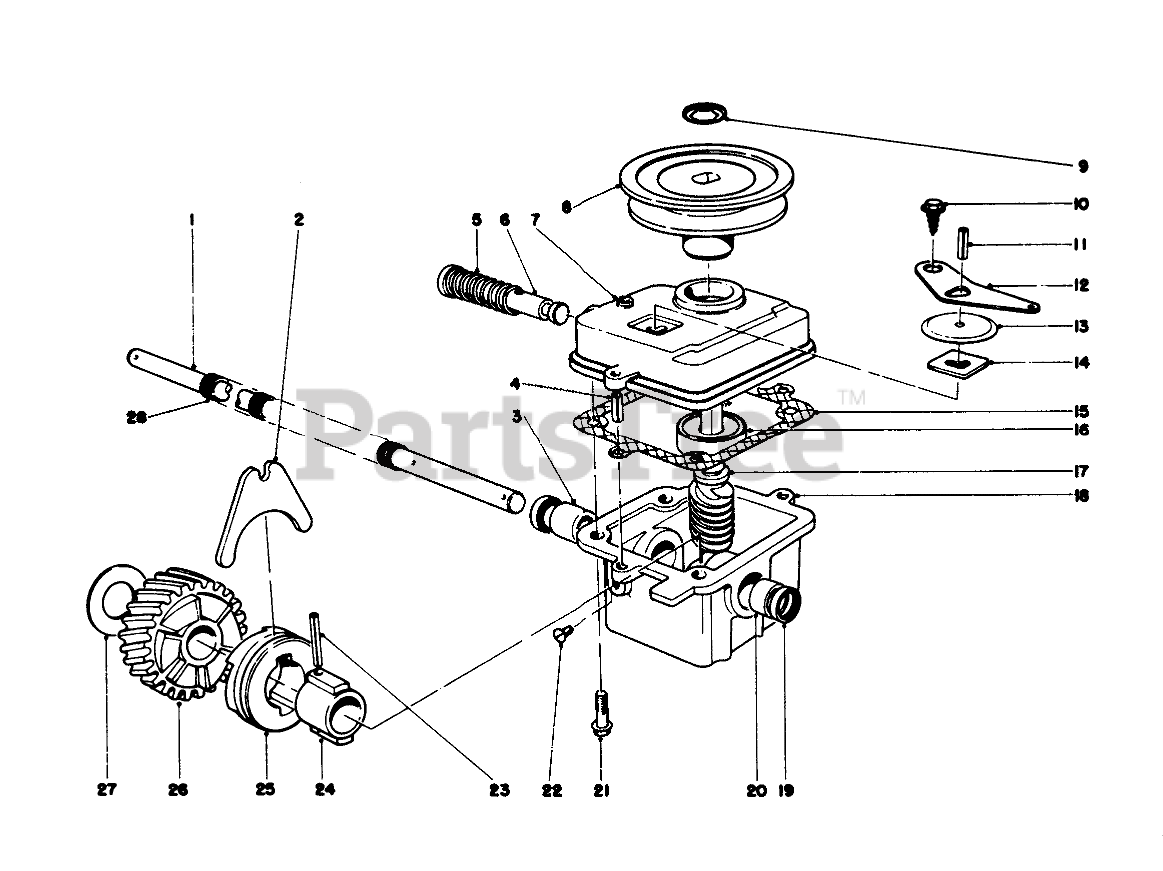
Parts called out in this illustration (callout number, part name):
1	Drive Shaft
2	SHIFTER FORK
3	Bushing
4	3/16 X 1/2 ROLL PIN
5	SPRING
6	Shift Rod
7	Cover Gear Case
8	PULLEY
9	PUSH-ON 93-3236
10	Screw
11	PIN-ROLL
12	SHIFTER ARM
13	TRANS DUST COVER
14	LATCH PLATE
15	GASKET
16	Bearing
17	Worm Shaft (Incl . Ref . #26)
18	Gear Case(Incl. Ref. #3,19-20)
19	Seal
20	Bushing
21	Screw
22	NYLON SCREW
23	COIL PIN
24	SLEEVE
25	CLUTCH JAW
26	Helical Gear
27	THRUST WASHER
28	DRIVE SHAFT COVER
